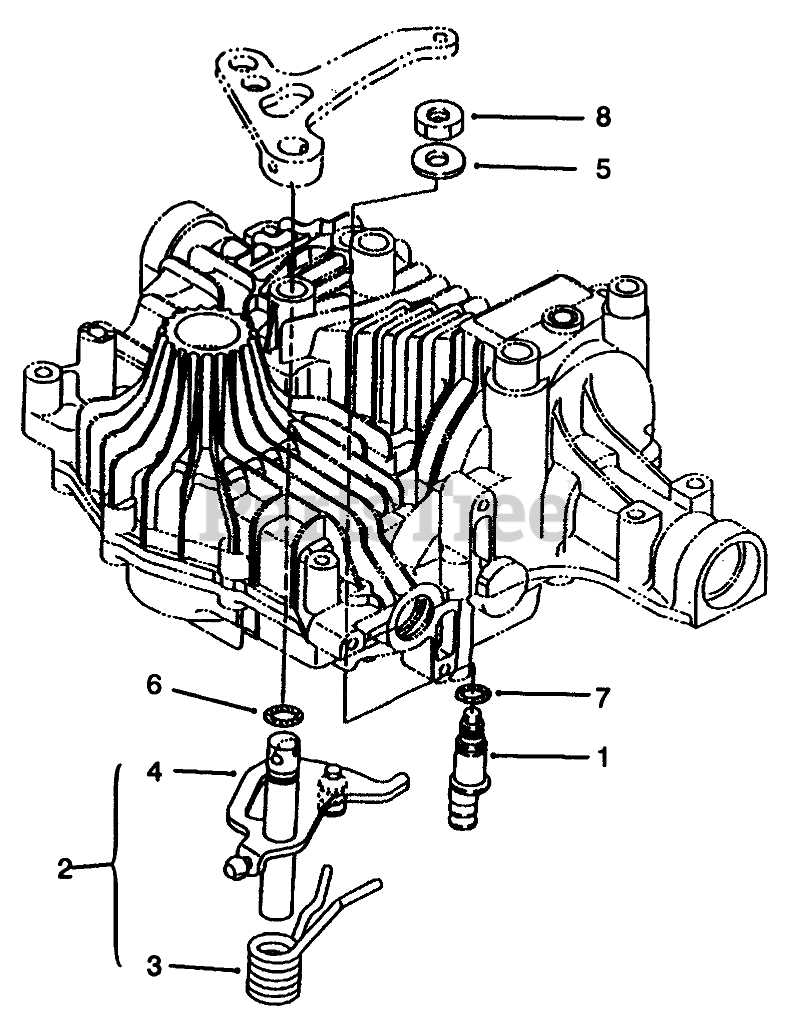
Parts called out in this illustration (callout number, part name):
1	FULCRUM
2	SHAFT ASM
4	Shaft-Control
5	WASHER
6	O-RING
7	PACKING
